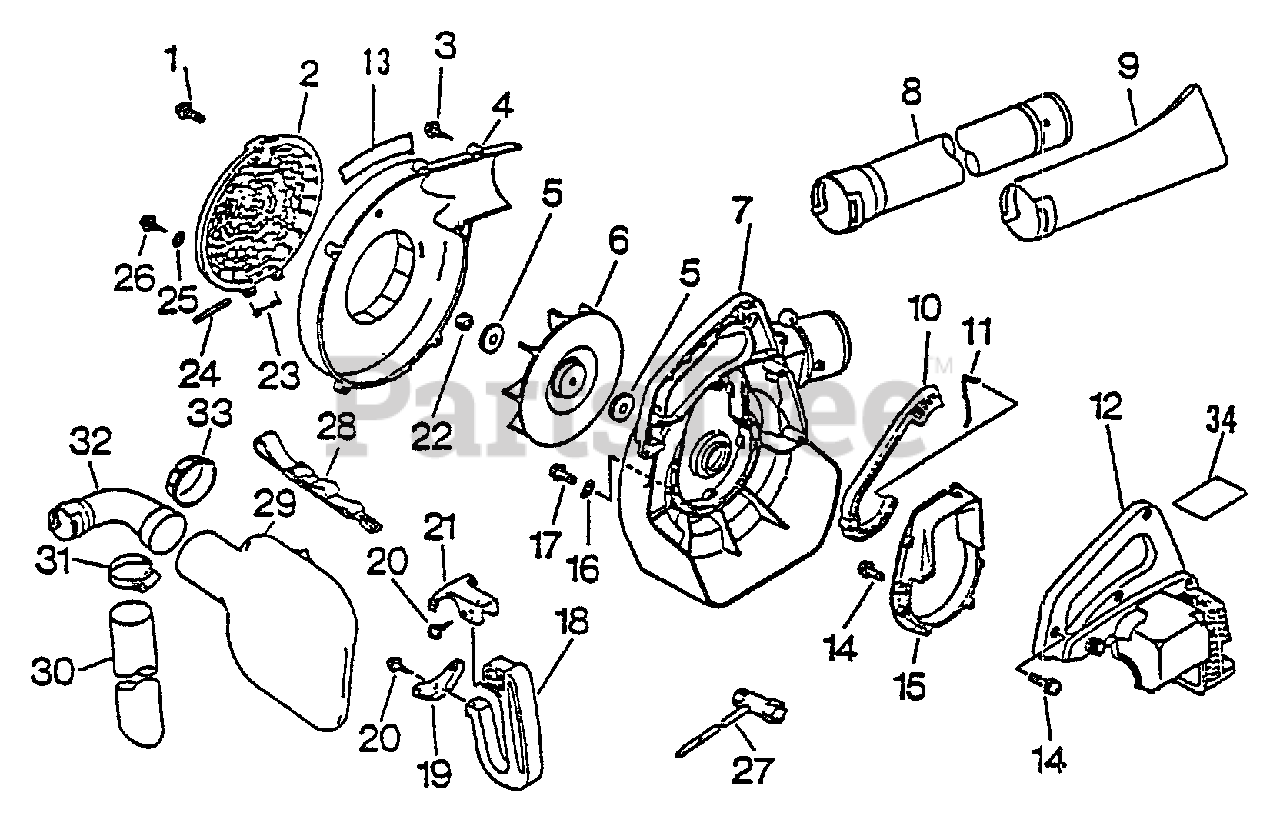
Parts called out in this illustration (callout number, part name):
1	THUMBSCREW
1	SCREW 5×18
2	SHIELD, DEBRIS
3	SCREW, TAPPING 5×20
4	COVER, FAN - RIGHT
6	FAN
7	COVER, FAN - RIGHT
8	TUBE, BLOWER
9	NOZZLE - FAN HEAD
10	TRIGGER, THROTTLE
11	ROD, THROTTLE
12	COVER, ENGINE
13	LABEL, LBH-2100
14	SCREW 4×18
15	BRACKET, ENGINE
17	SCREW 4×22
19	BRACKET, LOWER HANDLE
20	SCREW 5×14
21	BRACKET, UPPER HANDLE
23	SPRING, COIL
24	PIN, INTAKE COVER
26	SCREW 5×14
27	T-WRENCH 13×19×180
29	BAG, DUST
30	ADAPTER, TUBE
34	LABEL - CAUTION -- HOT
